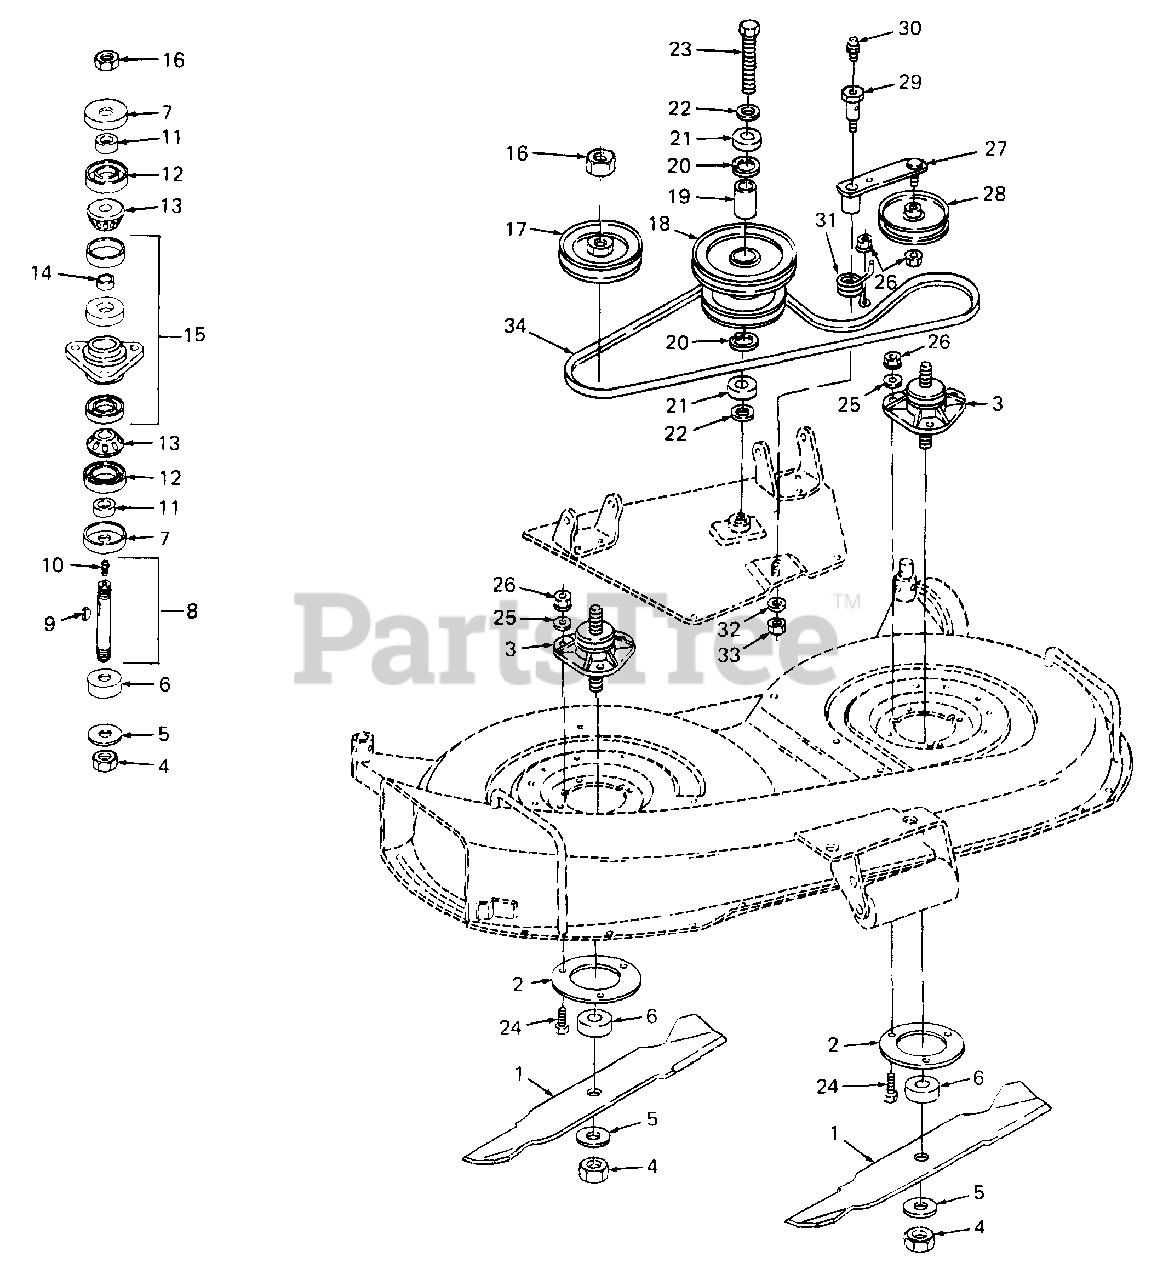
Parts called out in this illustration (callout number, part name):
1	Blade, Low Lift, 21.20 Lg
2	Plate, Spindle Mtg
3	Spindle Assy
4	Nut, Hex, 3/4-16 GR8
5	Washer, Flat, .781 X 2.0 X .105 Thk
6	Spacer
7	Cup, Spindle Hdn
8	Kit, Spindle w/Seal
9	Key, #91 Woodruff, 1/4 X 3/4 Hdn
10	Fitting, Lube, 3/16
11	Spacer, .755 X 1.25 X .44 Lg
12	Seal, Oil, 1.25 X 1.874 X .25
13	Cone, Bearing
14	Spacer, Bearing
15	Housing, Spindle w/Cups
16	Nut, Hex Jam, 3/4-16
17	V-Pulley, A-Sect X 4.70 OD
18	Pulley, Double
19	Spacer, Pulley, .635 ID X .88 OD X 2.15 Lg
20	Snap Ring, Internal
21	Bearing, Ball, .62 ID X 1.57 OD X .44 Thk
22	Washer, Flat, .63 X 1.0 X .063 Thk Hdn
23	Bolt, Hex, 5/8-18 X 4.25 Lg GR5
24	Screw, Hex Cap, 3/8-16 X 1.25 Lg GR5
25	Washer, Flat, .38 X 1.0 X .127
26	Nut, Hex Flanged Lock, 3/8-16
27	Arm Assy, Idler
28	Pulley, Flat Idler
29	Bolt, Shoulder
30	Fitting, Lube, 3/16
31	Spring, Torsion
32	Washer, Lock, 7/16
33	Nut, Hex, 7/16-14 GR5
34	V-Belt, A Sect X 69.0
